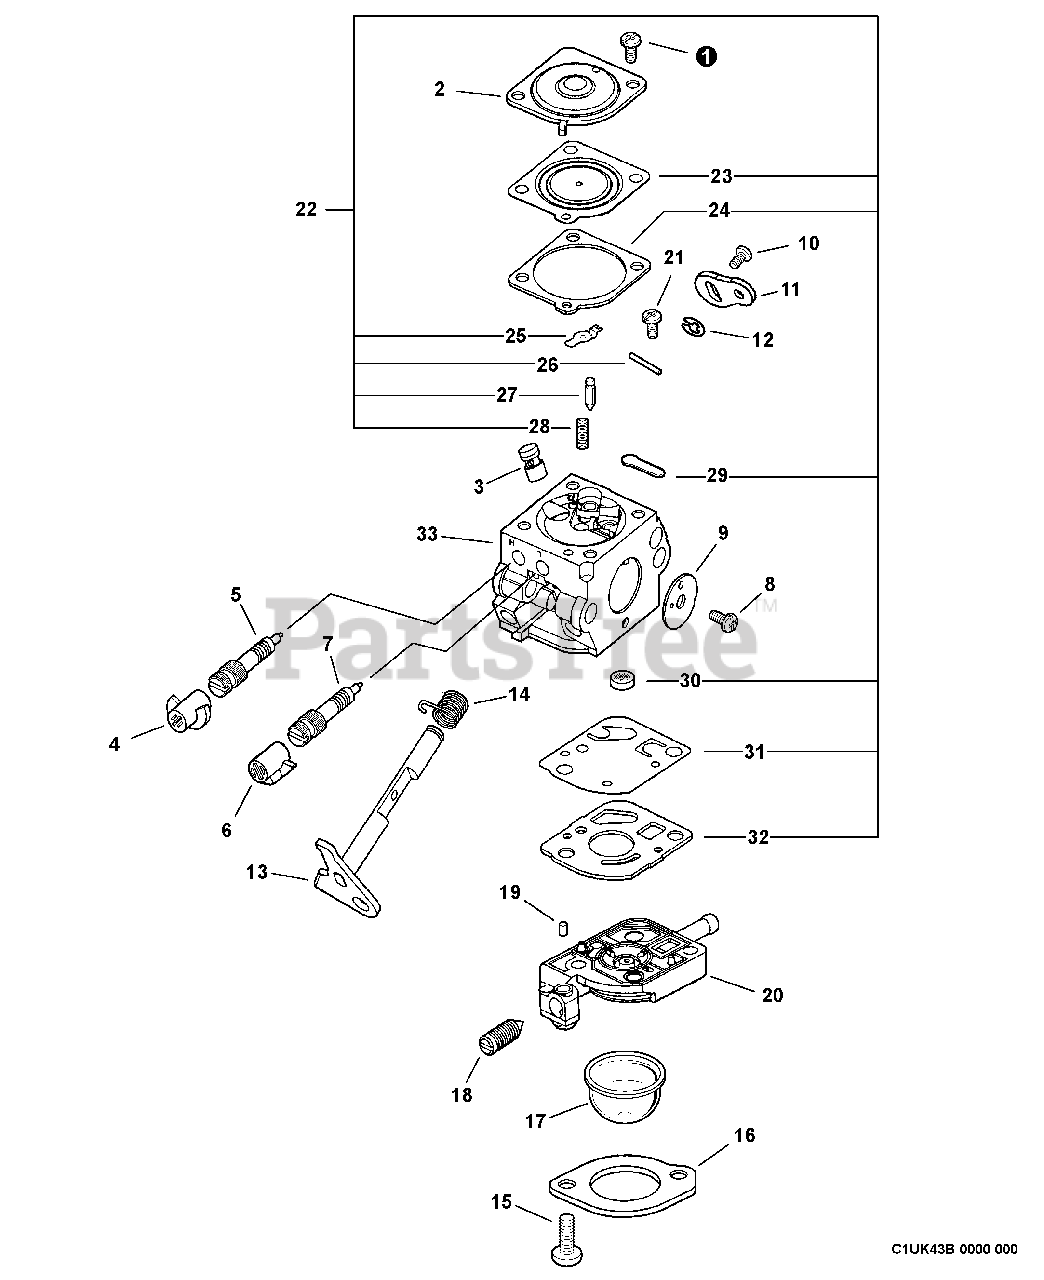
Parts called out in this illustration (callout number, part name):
2	COVER, METERING
3	NOZZLE, CHECK VALVE
4	CAP, LIMITER
5	NEEDLE - HIGH SPEED
6	CAP, LIMITER
7	NEEDLE - LOW SPEED
9	VALVE, THROTTLE
11	LEVER, THROTTLE
12	RING, RETAINING
13	SHAFT, THROTTLE
14	SPRING, TRIGGER
15	SCREW, RETAINER
16	RETAINER, PURGE BULB
17	BULB, PURGE
18	SCREW, IDLE ADJUST
19	PIECE, FRICTION
20	BASE, PURGE
21	SCREW, METERING LEVER PIN
22	REPAIR KIT
23	DIAPHRAGM
24	GASKET, DIAPHRAGM
25	LEVER, METERING
26	PIN, METERING LEVER
27	VALVE, INLET NEEDLE
28	SPRING, METERING LEVER
29	PLUG, WELCH
30	STRAINER
31	DIAPHRAGM, PUMP
32	GASKET, PUMP
33	BODY, CARBURETOR
